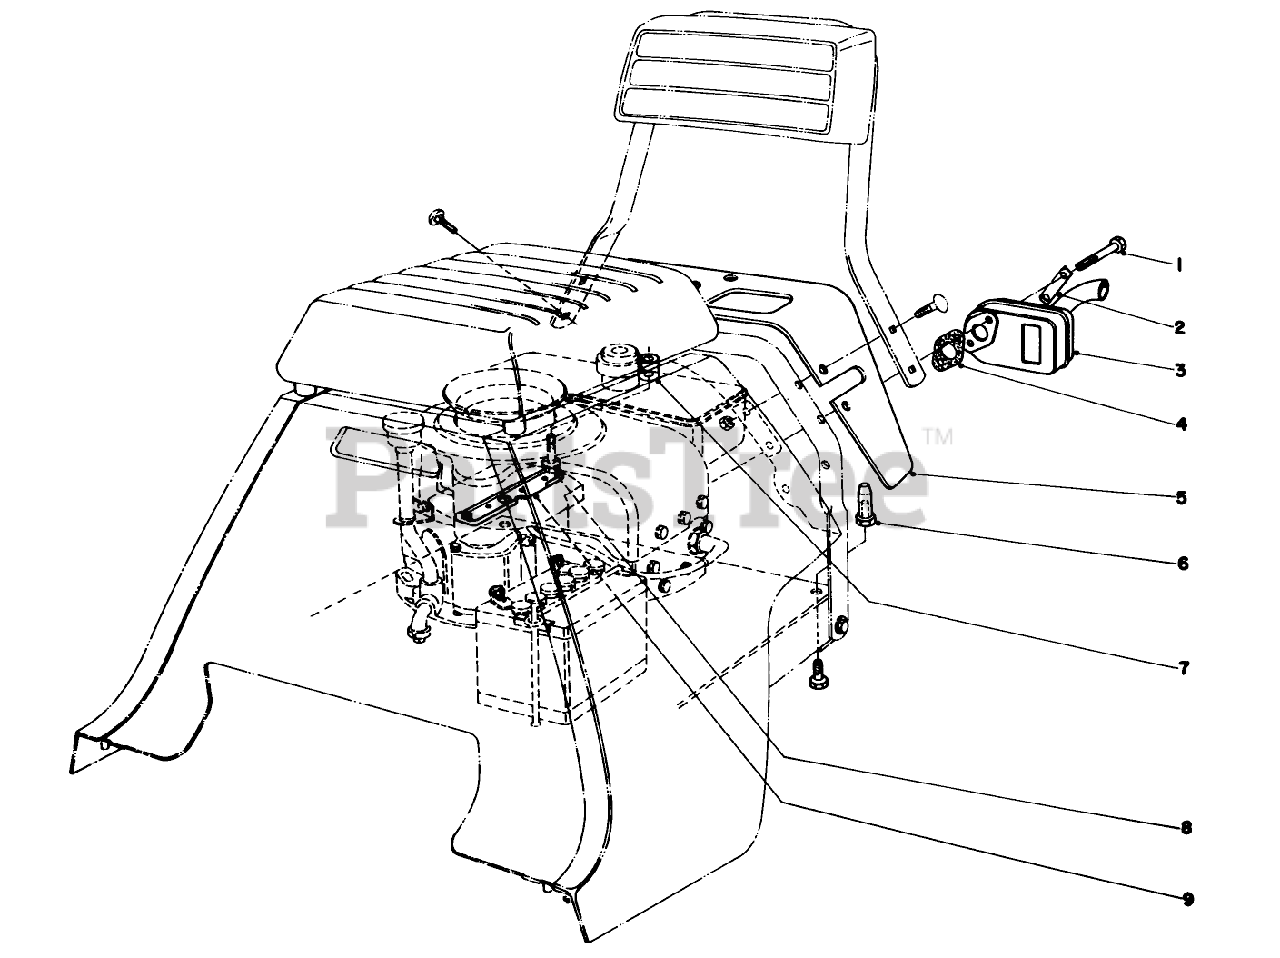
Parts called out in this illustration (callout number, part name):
1	Muffler Mounting Screw
2	Lock Plate
3	Muffler/Tail Pipe Assembly
4	Muffler Gasket
5	Extension Rear Body
6	PIN-MOUNTING, LOWER
7	Spacer
8	HEX FLANGE SCREW
9	Housing Bracket
